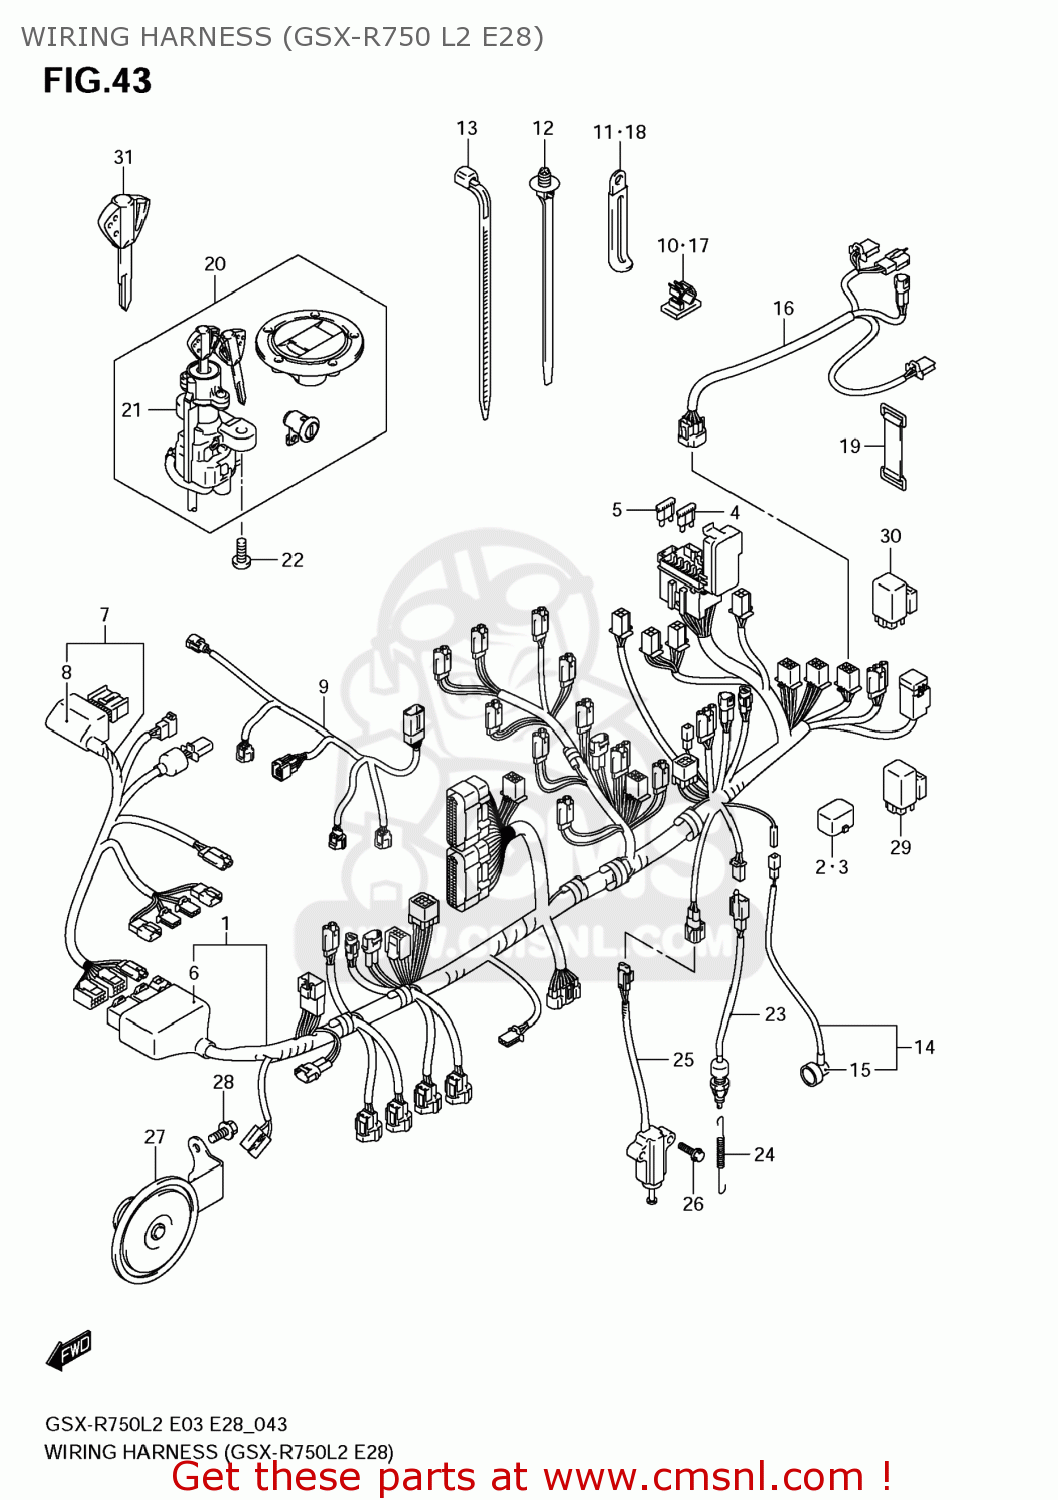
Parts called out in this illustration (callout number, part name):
1	HARNESS,WIRING NO.1
2	CAP,TS
3	CAP,CO ADJUST
4	FUSE(10A)
5	FUSE(15A)
6	COVER
7	HARNESS,WIRING NO.2
8	COVER,CONNECTOR
9	HARNESS,WIRING NO.3
10	CLAMP(L:95)
11	CLAMP(L:145)
12	CLAMP(L:154)
13	CLAMP(L:125)
14	WIRE,OIL PRESSURE SWITCH LEAD
15	CAP,OIL PRESSURE SWITCH
16	WIRE,RR COMB LEAD
17	CLAMP
18	CLAMP(L:45)
19	BAND
20	LOCK SET
21	LOCK ASSY,STEERING
22	BOLT(8X20)
23	SWITCH ASSY,STOP LAMP
24	SPRING
25	SWITCH ASSY,SIDE STAND
26	BOLT
27	HORN ASSY
28	BOLT
29	RELAY ASSY
30	RELAY ASSY
31	KEY,BLANK(IMMOBII)
